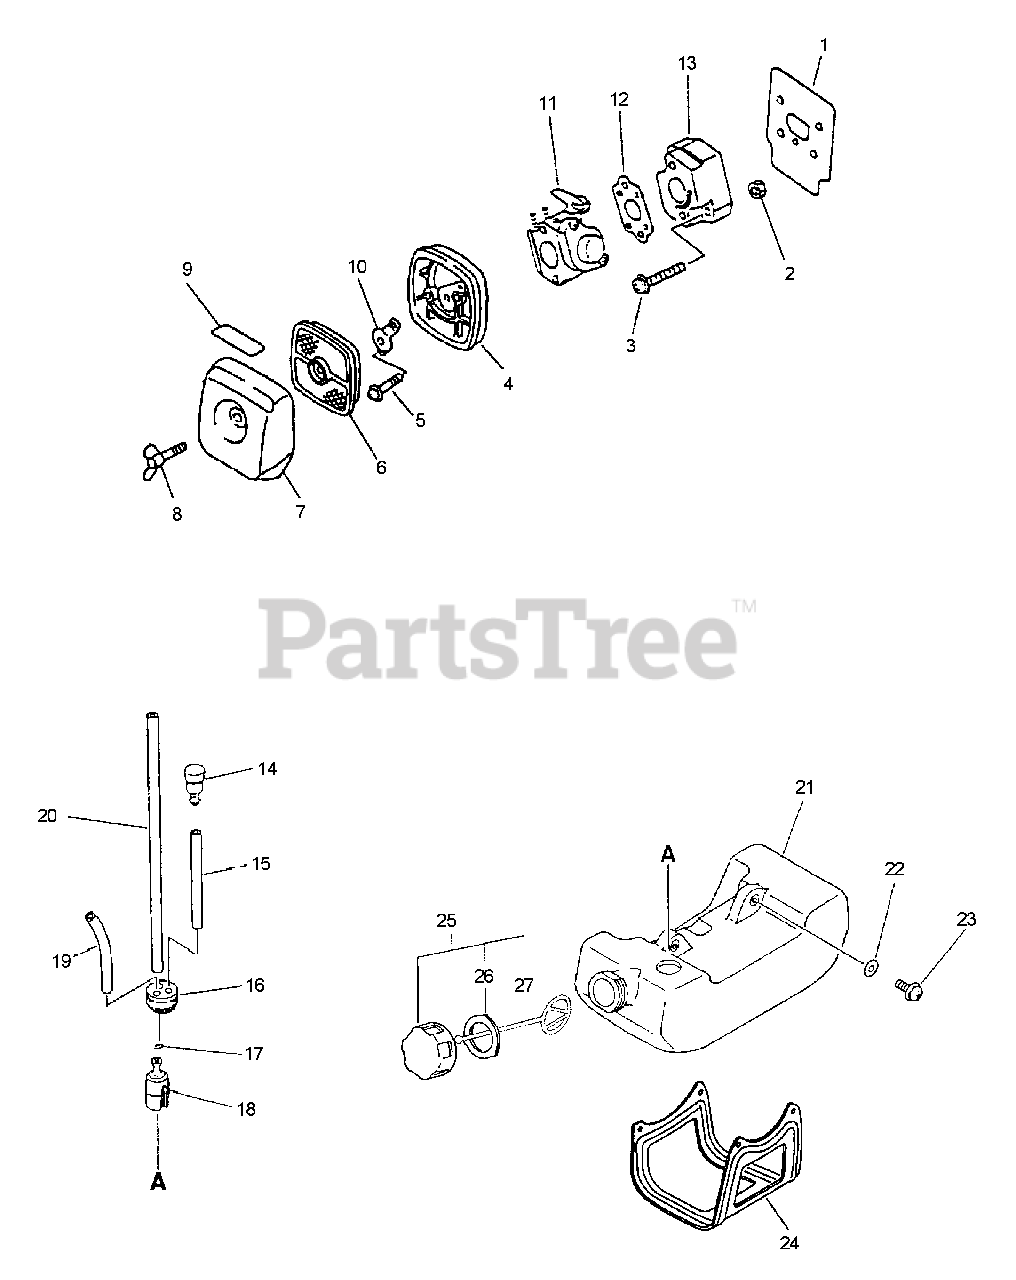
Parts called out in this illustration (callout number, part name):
1	SHIELD, INTAKE
3	SCREW - 5X20
4	AIR FILTER CASE ASSY
5	SCREW - 5X65
6	FILTER, AIR - SINGLE LAYER
7	COVER, AIR FILTER - BLACK
8	THUMBSCREW
9	LABEL - CHOKE
10	PLATE, PREVENT
11	CARBURETOR C1U-K52
12	GASKET, INTAKE
13	INSULATOR, INTAKE
14	VENT, FUEL TANK
15	PIPE - 3X5X70 -- BLACK
16	GROMMET
17	CLIP - 6
18	FILTER, FUEL
19	PIPE - 3X6X90 -- CLEAR
20	PIPE - 3X5X180 -- BLACK
21	FUEL TANK ASSY
22	WASHER - 5
23	SCREW - 5X16
24	GUARD, FUEL TANK
25	CAP ASSY
26	GASKET, CAP
27	CONNECTOR, CAP
